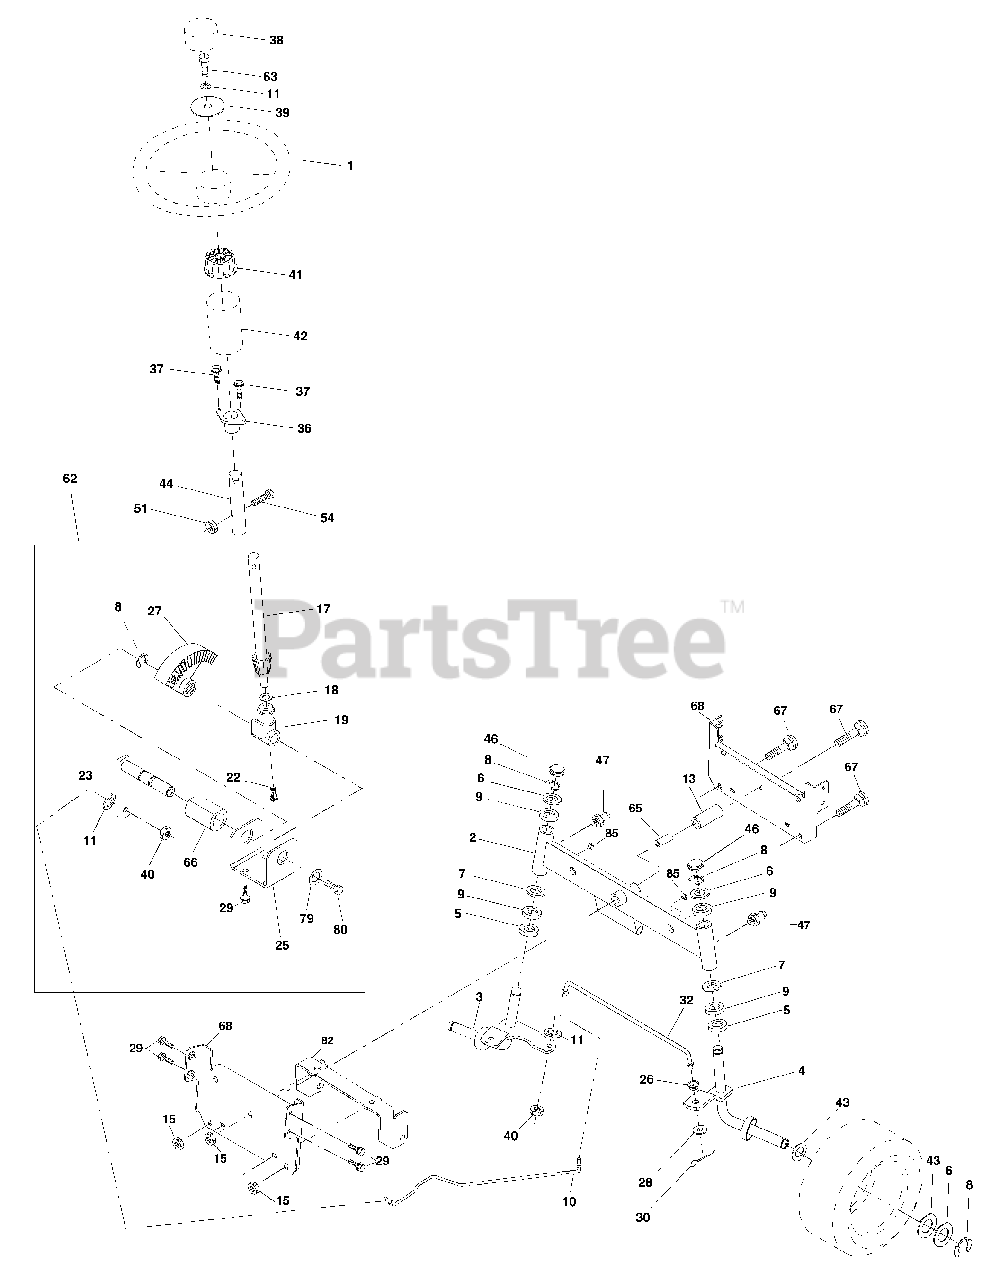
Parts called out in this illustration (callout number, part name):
1	Wheel Steering
2	Axle Asm
3	Spindle Asm LH
4	Spindle Asm RH
5	Bearing Race Thrust Harden
6	Washer 25/32 X 1-5/8 X 16 Ga
7	Washer 27/32 X 1-1/4 X 16 Ga
8	Ring Klip #t5304-75
9	Bearing Col Strg Blk
11	Washer Lock Hvy Hlcl Spr 3/8
13	Spacer earing Axle Front
15	Hexflange Lock
17	Shaft Asm Strg
18	Washer Thrust 515x 750x 033
19	Support Shaft
22	Screw Hex Wsh Hd Torx
23	Shaft Asm Pittman
25	Bracket Steering
26	Bushing Link Drag Blk LR
27	Gear Sector
28	Washer 13/32 X 7/8 X 16 Ga
29	Screw 3/8-16 x 3/4
30	Pin Cotter 1/8 X 3/4 Cad
32	Rod Tie Wire Form 19 75 Mech
36	Bushing Strg 5/8 Id Dash
38	Cap Wheel Steer
39	Washer 13/32 x 2-3/8 x 12 Ga.
40	Nut Lock Center 3/8-24un
41	Adaptor Wheel Strg
42	Boot Dash Mtl Steering Blk
43	Washer 25/32 X 1 1/4 X 16 Ga
44	Extension Steering
46	Cap Spindle Fr Top Blk
47	Fitting Grease
51	Nut Lock Hex W/Ins 5/16-18
54	Bolt Fin Hex 3/8-16unc x 1-1/4
62	Kit Steering Assembly Service
63	Bolt Fin Hex 3/8-16unc x 1 Gr.5
65	Spacer Brace Axle
66	Bearing Arm Pittman
67	Bolt Fin Hex 5/8-11 unc x 2-3/4
68	Brace Axle
79	Washer 13/32 x 1 1/4 x 12 Ga.
80	Bolt Hex 3/8-16 x 3/4
82	Bracket Susp Chassis Front
85	Fastener Christmas Tree
